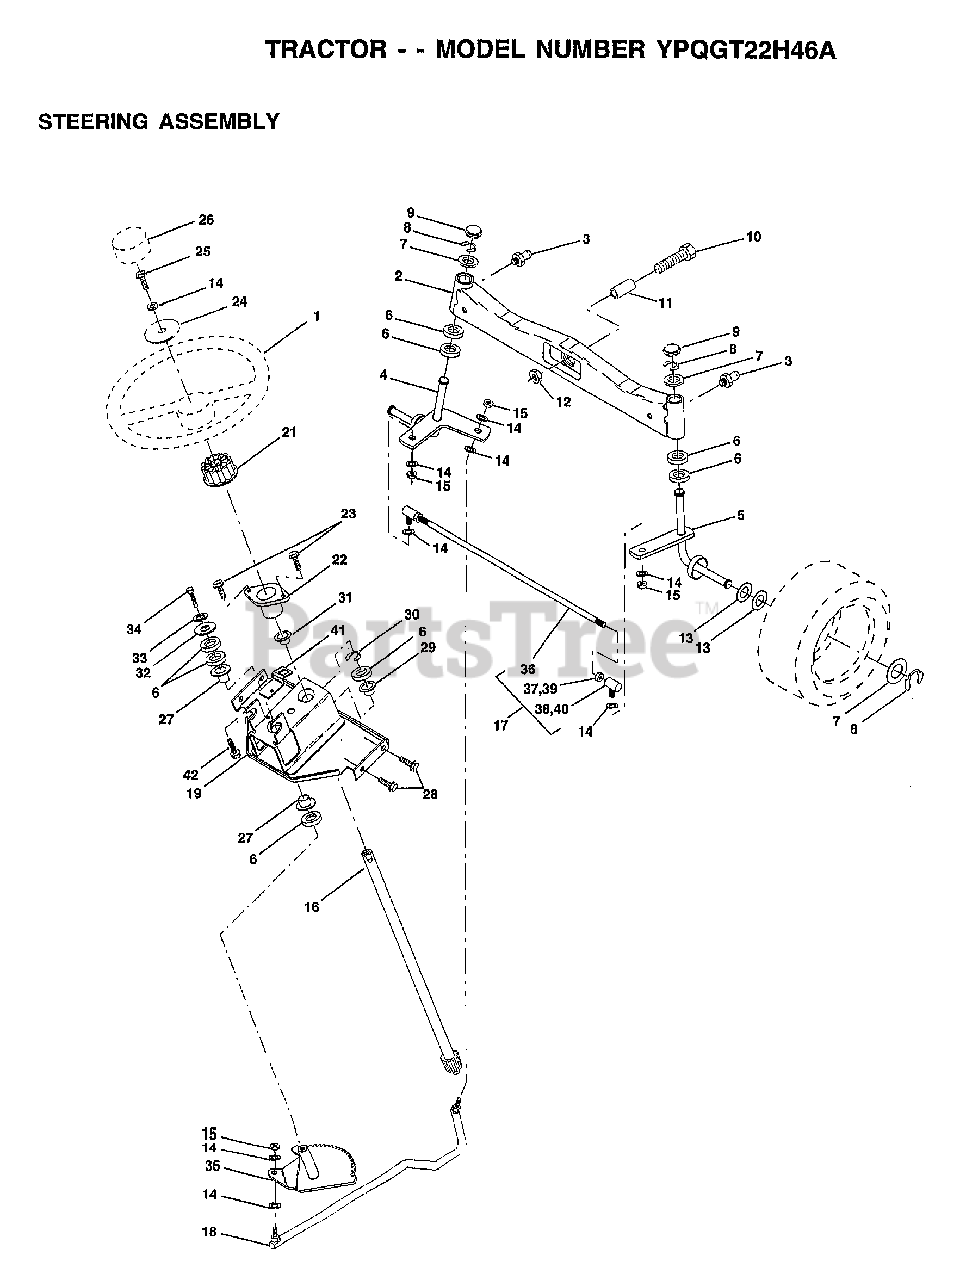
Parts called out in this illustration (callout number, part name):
3	ZERK M
4	SPINDLE ASM LH
5	SPINDLE ASM RH
6	WASHER .T
7	WASHER
8	RING
9	CAP
10	BOLT
11	SPACER BEARING
12	"NUT-LOC,FLANGE LT"
13	WASHER
14	LOCKWASHER
15	GRIPCO NUT
16	SHAFT.STEER.VGT
17	ROD.ASM.TIE.BALL
18	DRAGLINK.BALL.JOI
19	SUPPORT ASM-STEER
21	ADAPTER LT
22	"BUSHING,STEERING"
23	"SCREW-TT,10-32 FL"
24	WASHER
25	BOLT
26	"INSERT,STR WHEEL"
27	COL. SRTG. BEAR.
28	SCREW
29	"FLANGE GT, BEAR."
30	KLIP RING
31	BUSHING.NYLINER.
32	WASHER
33	LOCKWASHER
34	BOLT
35	GEAR.ASM.SECTOR.
37	NUT
38	JOINT.RH
39	NUT
40	JOINT.LH
41	"BRKT-SW, INTER"
42	SCREW LT
